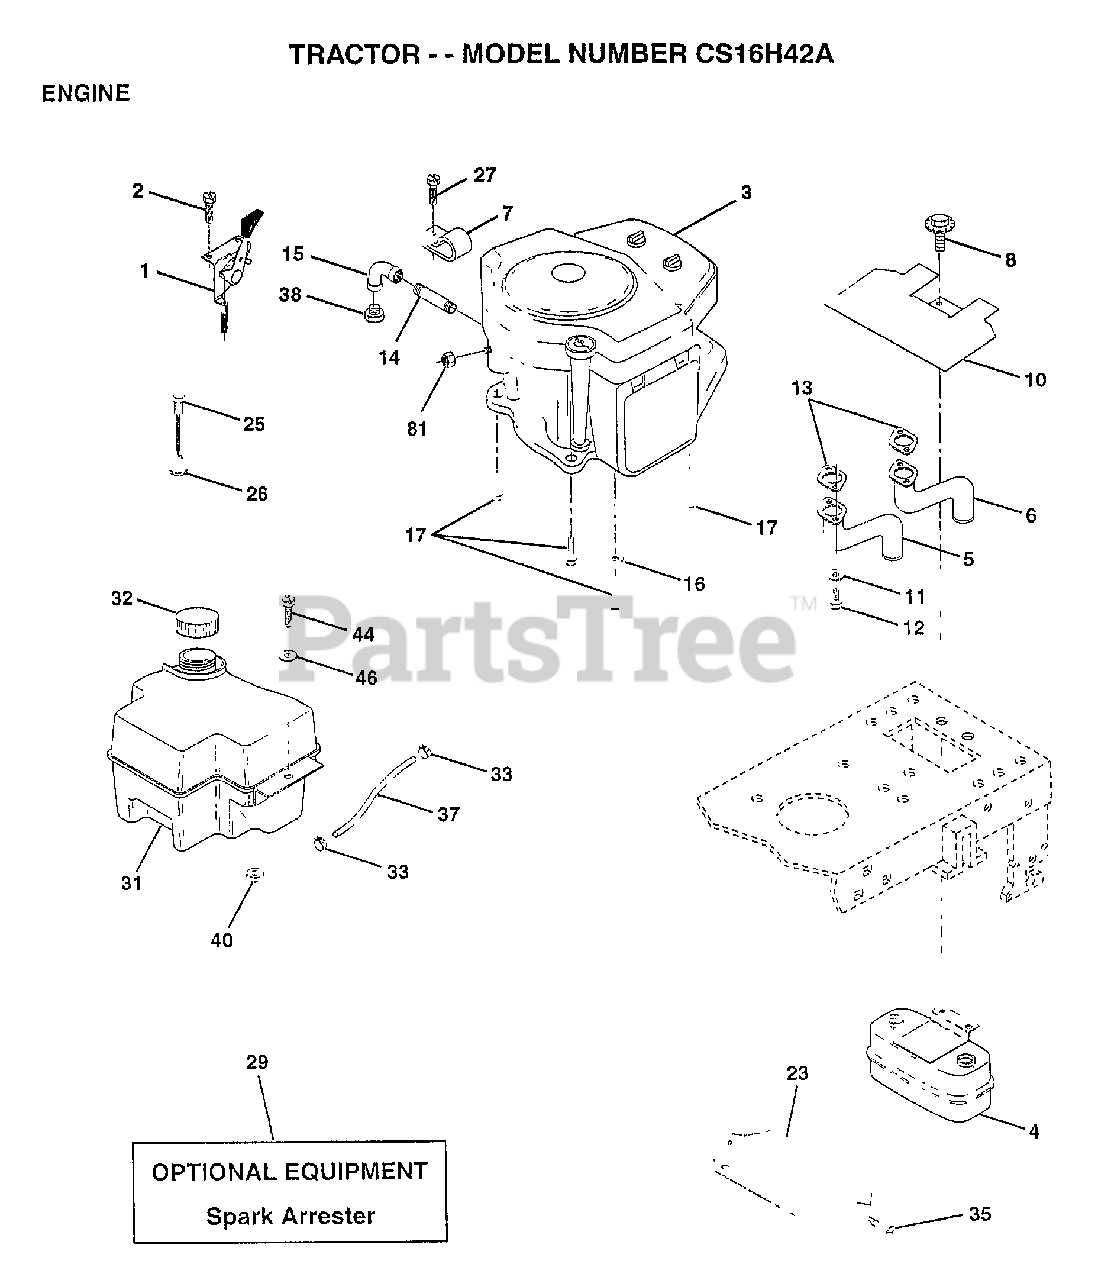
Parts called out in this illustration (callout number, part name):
1	CONTROL THRT 35.5
2	SCREW LT
3	ENGINE, BRIGGS
4	MUFFLER.TW.LOTONE
5	EXHAUST.B&S.18.LH
6	EXHAUST.B&S.18.RH
7	CLAMP.TUBE.DBL.EN
8	BOLT.5/16-18.UNC
10	SHIELD.HEAT.
11	LOCKWASHER
13	GASKET MUFFLER
14	PIPE NIPPLE LT
15	ELBOW
16	LOCKWASHER
17	SCREW LT
23	SHIELD-HEAT
25	CONTROL.CHOKE.37
26	"NUT,KEPS 3/8-24IM"
27	"SCREW-TT,10-32 FL"
32	CAP ASM FUEL
33	HOSE CLAMP
35	SCREW
37	LINE FUEL
44	SCREW HEX CRT
46	WASHER
81	NUT
